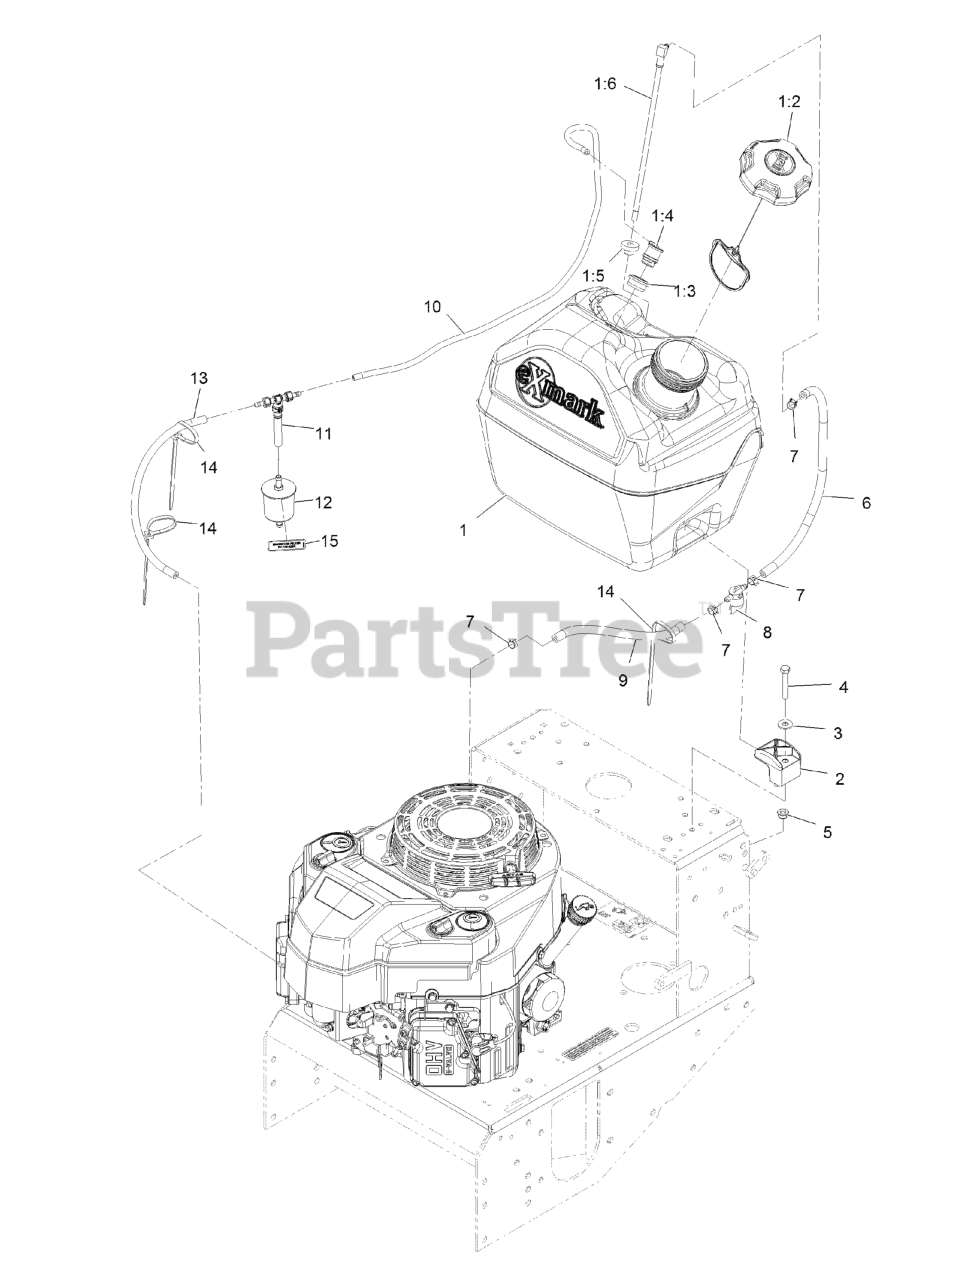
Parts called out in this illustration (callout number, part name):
1	ASM, FUEL TANK 5 GAL
1:2	CAP-FUEL, RATCHETING
1:3	GROMMET
1:4	VALVE-VENT, FUEL
1:5	BUSHING
1:6	FITTING, FUEL W/LINE AND SCREEN
3	WASHER-FLAT
4	SCREW-HH
5	NUT-HF, NI
6	HOSE-FUEL
7	CLAMP-HOSE
8	VALVE-FUEL
9	HOSE-FUEL
10	HOSE-EMISSIONS
11	TEE AND CHECK
12	FILTER-FUEL
13	HOSE-FUEL
14	TIE-PLASTIC
15	DECAL-FILTER, EMISSIONS
